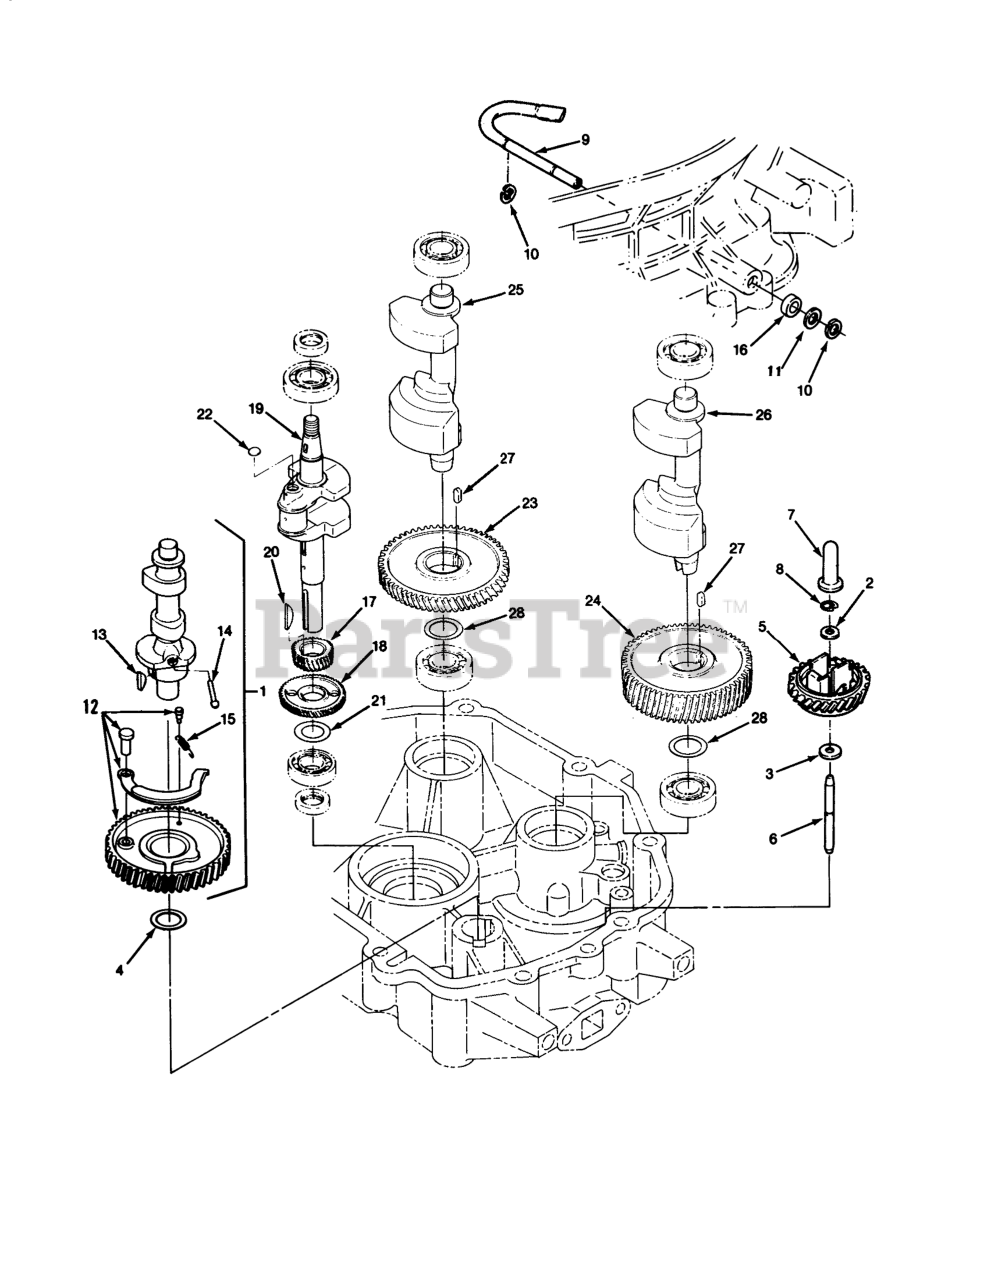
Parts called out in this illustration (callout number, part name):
1	Camshaft Assembly (Incl. Ref. #12-15)
2	WASHER-1.6MM THK
3	WASHER-1MM THK
4	SHIM-CAMSHFT 0.5MM
5	GEAR-GOVERNOR
6	SHAFT-GOVERNOR
7	Sleeve
8	STOP-GOVERNOR
9	SHAFT-GOVERNOR LEVER
10	CLIP-RETAINER
11	Nut-M8
12	CAMGEAR ASS'Y
13	KEY-CAMGEAR
14	PIN-DECOMPRESSION
15	SPRING-DECOMPRESSION
16	SEAL-GVR SHAFT LEVER
17	GEAR-CRANKSHAFT
18	GEAR-BALANCER
19	Crankshaft
20	KEY-CRANKSHAFT GEAR
21	SHIM-CRANKSHFT 0.2MM
22	PLUG-EXPANSION
23	GEAR-BALANCER
24	GEAR-BALANCER
25	SHAFT-BALANCER
26	SHAFT-BALANCER
27	KEY-BALANCER GEAR
28	SHIM-BAL SHAFT 0.5MM
